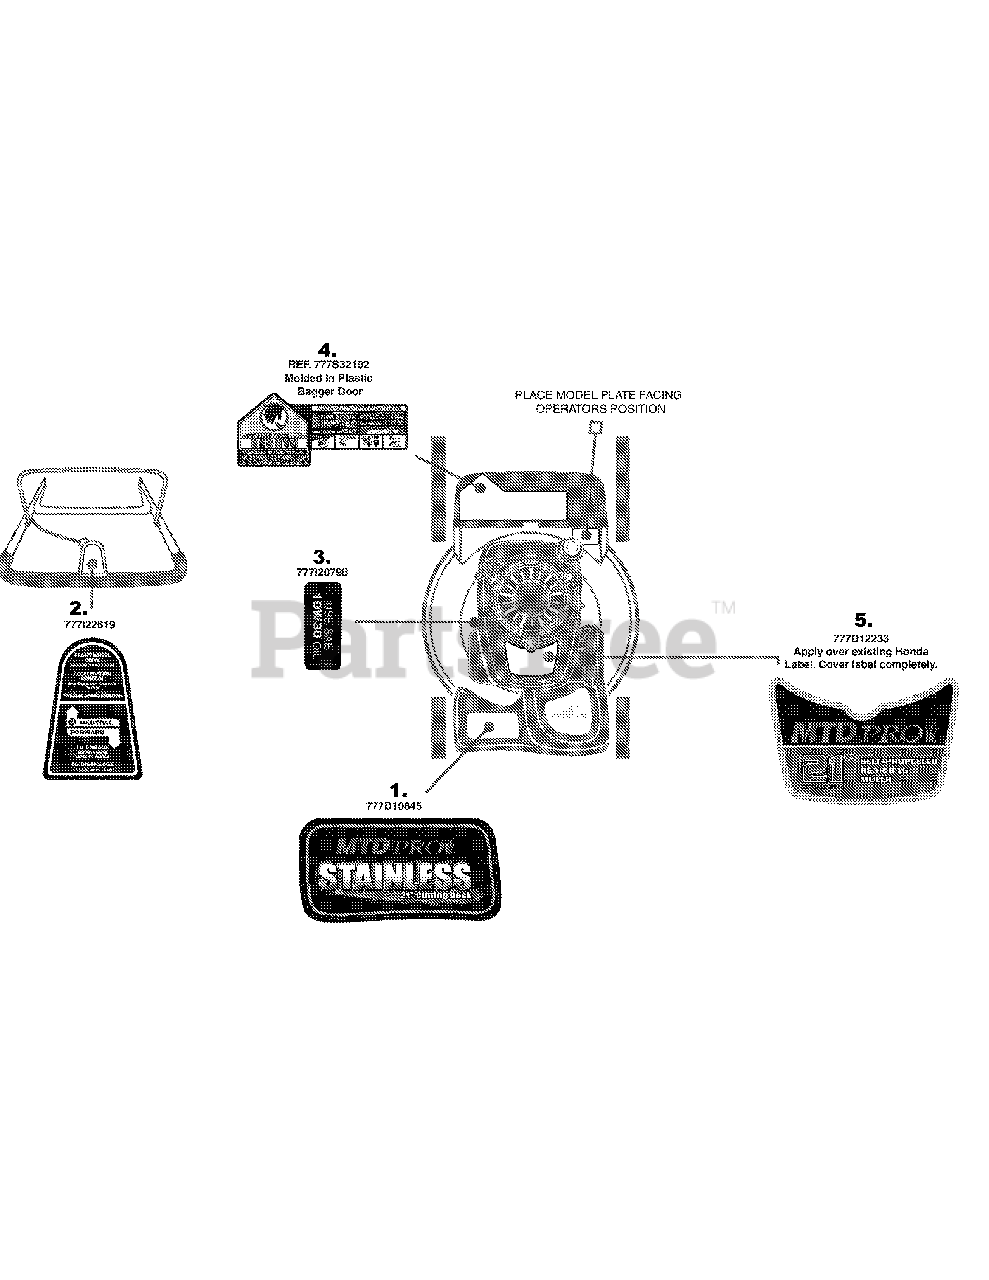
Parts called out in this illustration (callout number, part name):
1	LABEL:MOWER:FDC:MTD PRO STNLESS
2	LABEL-MOWER SQ LEVER
3	LABEL-SHROUD
4	LABEL
5	LABEL:MOWER SHROUD
